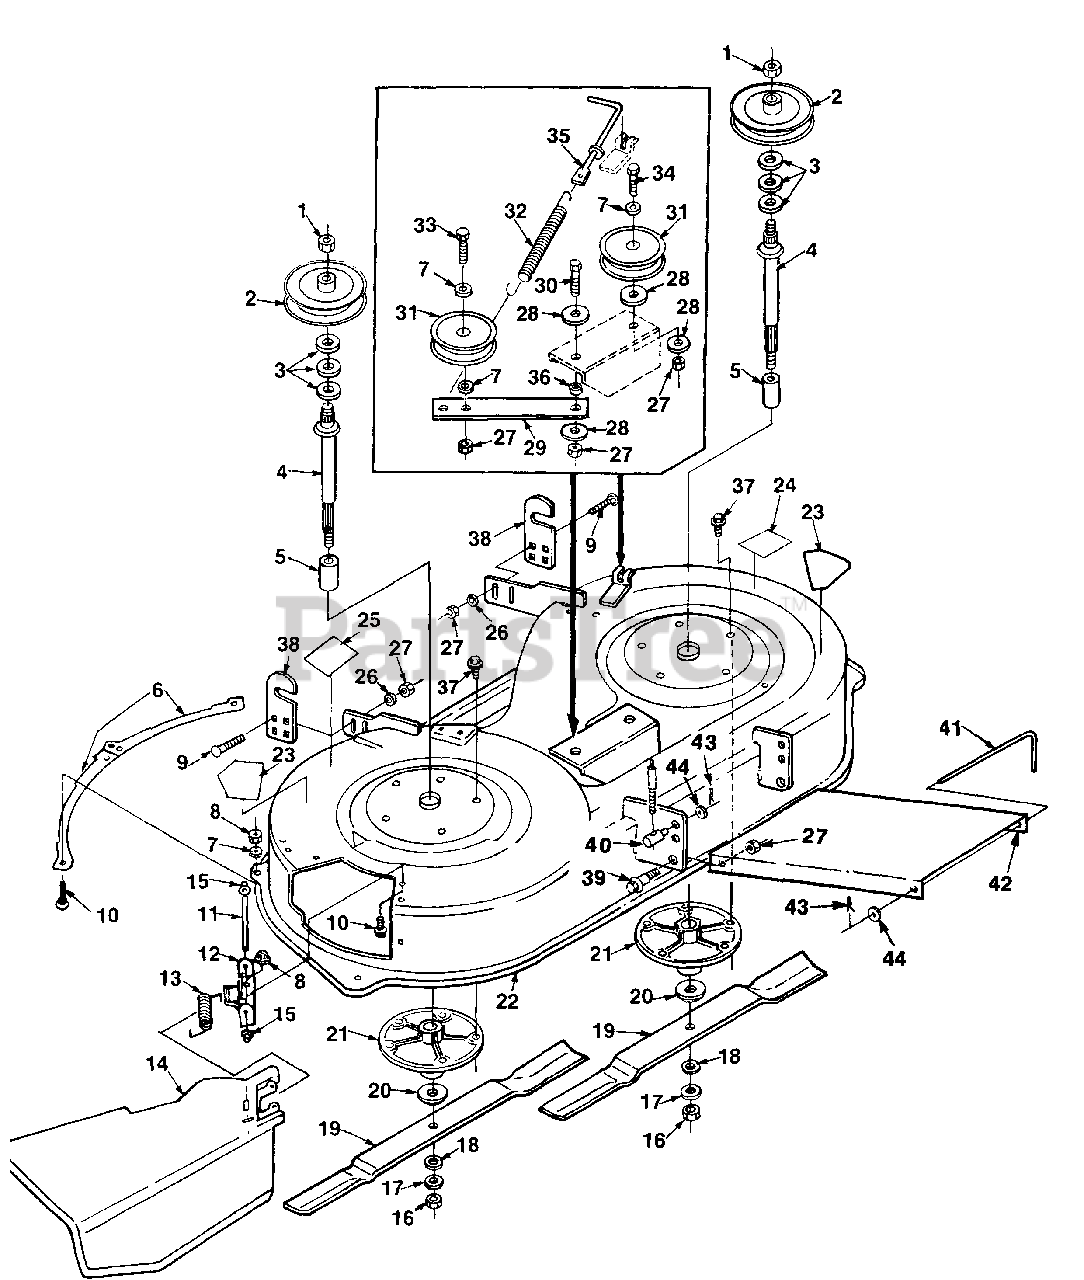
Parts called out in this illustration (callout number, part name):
1	NUT- Center lock (9/16-18)
2	PULLEY- Cutter head
3	WASHER- Flat
4	SPINDLE- Cutter head
5	SPACER- Spindle
6	PLATE- Air cut off
7	WASHER- Flat (3/8")
8	NUT- Flange (5/16-18)
9	BOLT- Rd. hd., sq. neck (3/8-16 x 1 1/4")
10	BOLT- Rd. hd.. sq. neck
11	ROD- Deflector
12	BRACKET- Chute hinge
13	SPRING- Torsion
14	CHUTE- Deflector Assy
15	NUT- Pal, push (3/8")
16	NUT- Hex (9/16-18)
17	WASHER- Flat
18	WASHER- Belleville
20	BLADE- Adaptor
21	HOUSING- Spindle
22	DECK ASSEMBLY
23	DECAL- Danger
24	DECAL- No step
25	DECAL- Belt installation
26	WASHER- Flat
27	NUT- Hex lock (3/8-16)
28	WASHER- Blade mtg
29	ARM- Idler
30	SCREW- Hex hd., cap (3/8-16 x 1 1/2")
31	PULLEY- Idler
32	SPRING- Extension
33	SCREW- Hex hd., cap (3/8-16 x 1 3/4")
34	SCREW- Hex hd., cap (3/8-16 x 2")
35	ROD- Spring release
36	SPACER- Idler arm
37	SCREW- Hex washer hd.
38	BRACKET- Rear hanger
39	BOLT- Shoulder
40	PIN- Clevis
41	PIN- Link
42	BRACKET- Link
43	PIN- Hair cotter
44	WASHER- Flat
